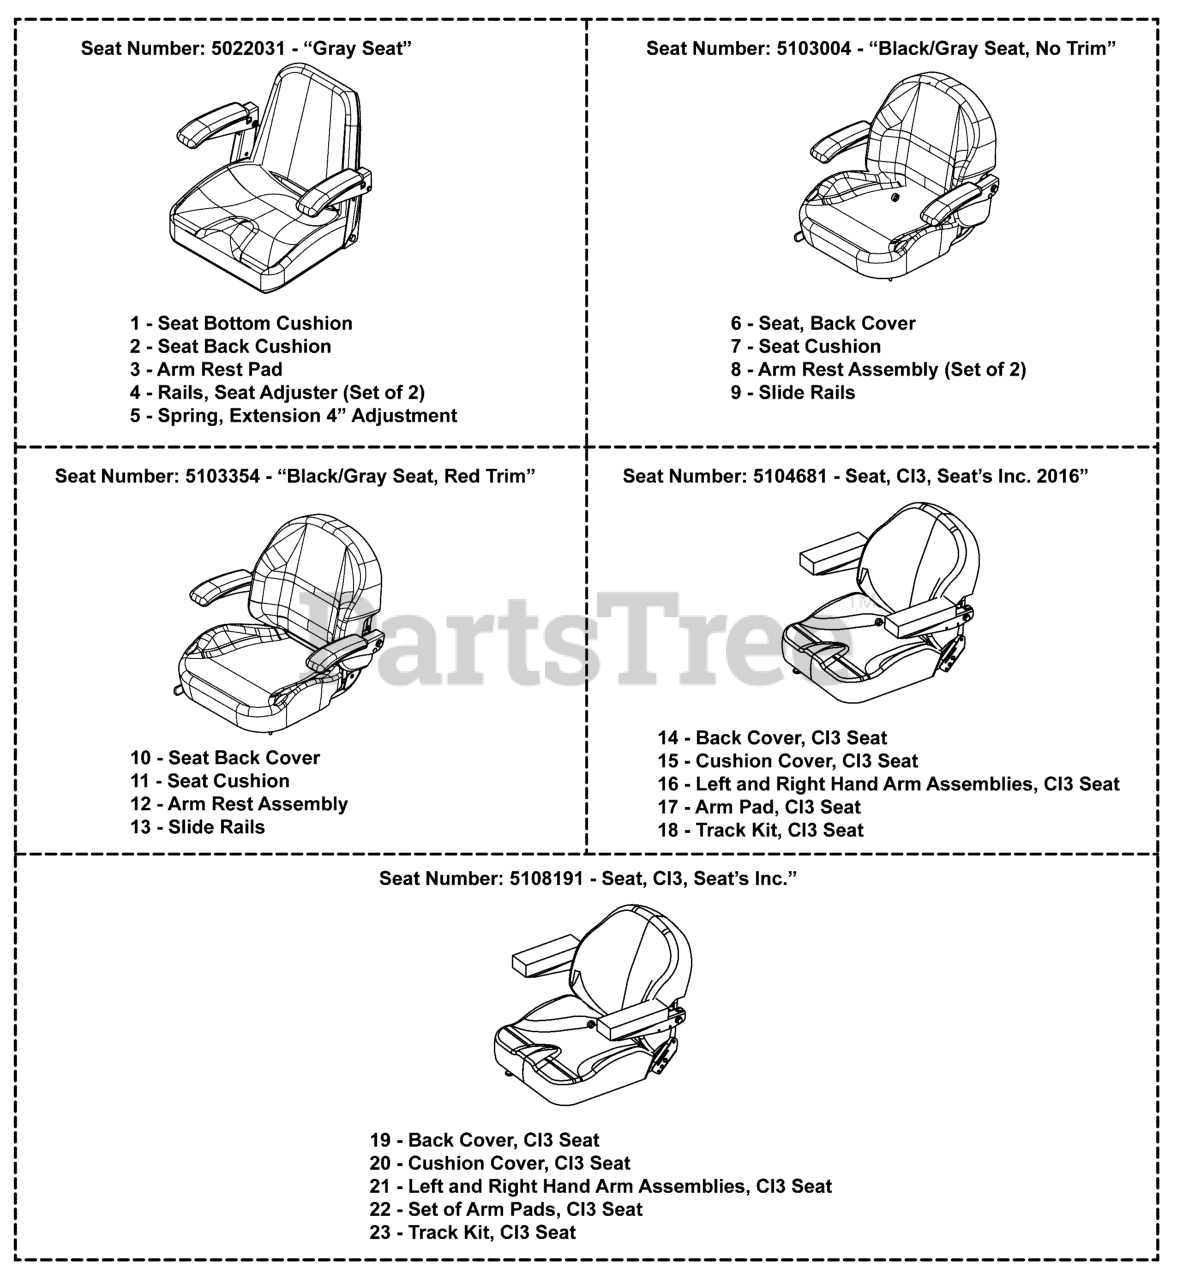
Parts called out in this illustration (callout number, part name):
1	SEAT BOTTOM (EVC 907)
2	CUSHION, SEAT BACK, GRAY
3	ARM REST, BLACK MOLDED, PAD ONLY
4	RAILS, SEAT ADJUSTER (SET OF TWO)
5	SPRING, EXTENSION, SEAT ADJUSTMENT (YEL OR BLK)
6	SEAT BACK COVER
7	SEAT CUSHION
8	Arm Rest Asm. (set of 2)
9	SLIDE RAILS
10	SEAT BACK COVER, SEAT 2012
11	SEAT COVER
12	Arm Rest Asm. (set of 2)
13	SLIDE RAILS
14	BACK, COVER, CI3 SEAT
15	CUSHION COVER, CI3 SEAT
16	LEFT AND RIGHT HAND ARM ASSEMBLIES, CI3 SEAT
17	ARM PAD, C13 SEAT
18	TRACK KIT, CI3 SEAT
19	CUSHION, Back
20	CUSHION COVER FOR CI3
21	CUSHION COVER FOR CI3
22	ARM PAD ASSEMBLY
23	TRACK KIT, CI3 SEAT
